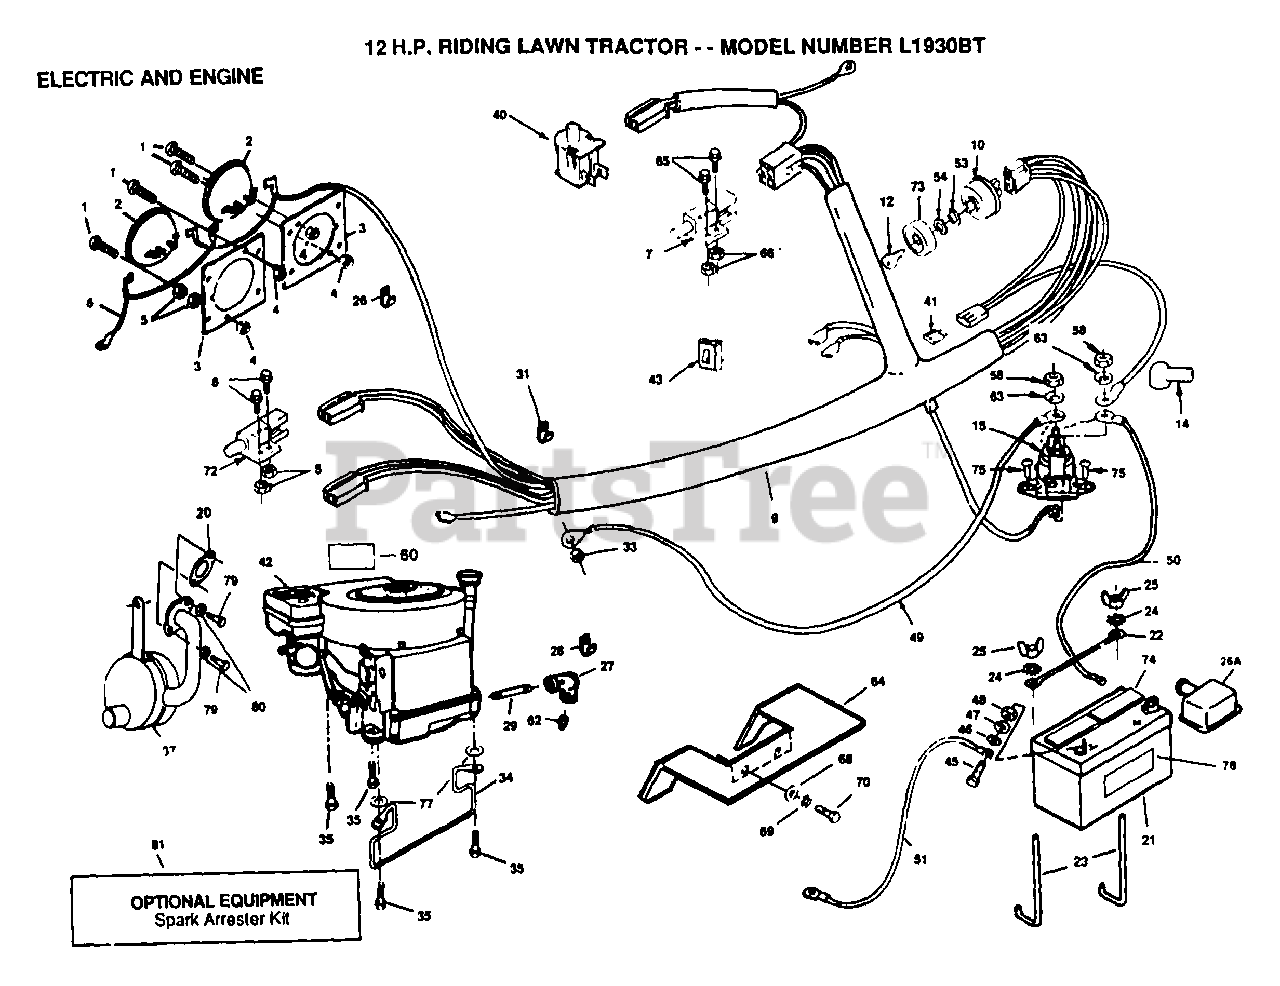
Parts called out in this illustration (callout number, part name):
7	SWITCH INTERLOCKT
8	SCREW
17	NUT
23	"BOLT, BATTERY"
24	LOCKWASHER GT
26	CLIP SB
26A	BATTERY TERMINAL COVER
27	ELBOW
28	INSUL CLIP T
29	PIPE NIPPLE
34	BELT KEEPER LT
35	SCREW LT
40	SWITCH SEAT
41	FUSE HYT
43	SWITCH LT
45	BOLT LT
46	WASHER
47	LOCKWASHER
49	"CABLE T, BATTERY"
53	WASHER T
58	NUT
59	DECAL.ENG.27164
62	PLUG OIL DRAIN
64	SHIELD HEAT LT
65	SCREW
66	"NUT,KEPS"
69	LOCKWASHER
72	SWITCH-INTER. GT
74	"CAP,BATTERY "
75	"SCREW,MACHINE"
77	WASHER
78	DECAL
79	BOLT
80	LOCKWASHER
81	SPARK ARRESTER KIT
